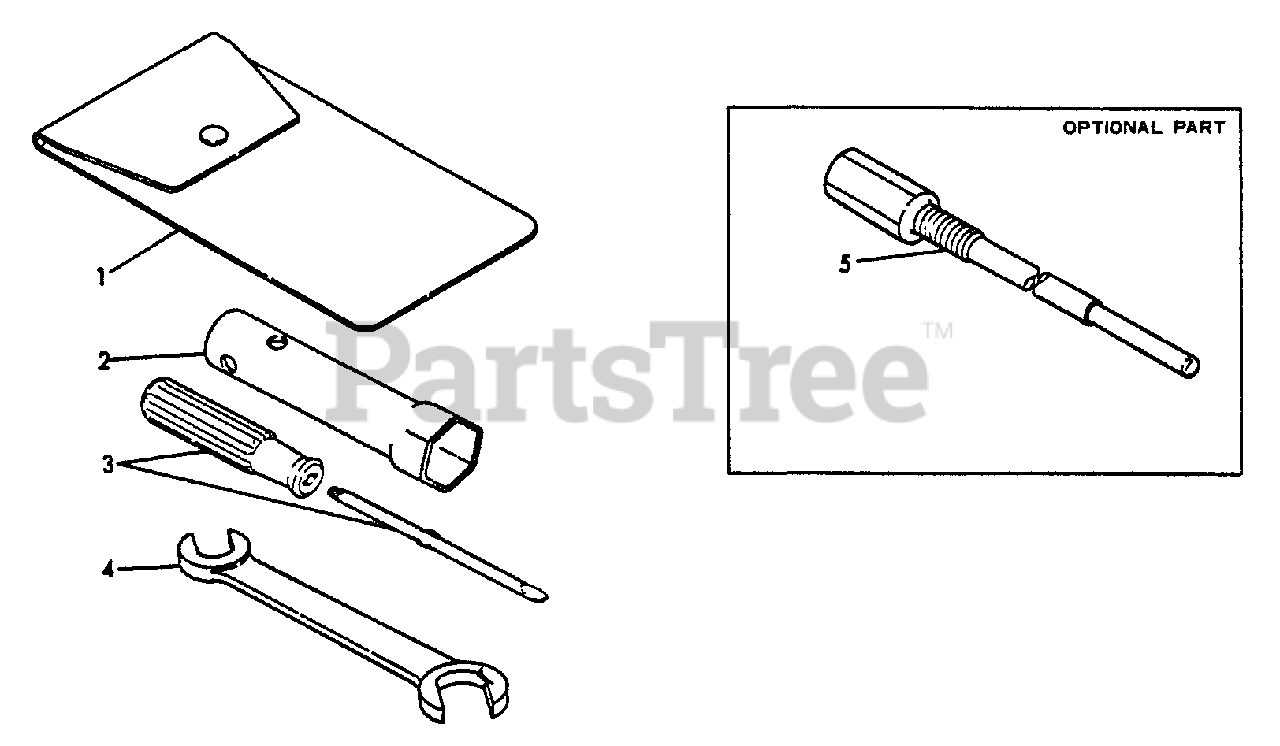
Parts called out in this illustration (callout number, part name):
1	BAG, TOOL
2	BOX SPANNER - 21
3	SCREWDRIVER
4	WRENCH 10×12
5	REMOVER, ROTOR
